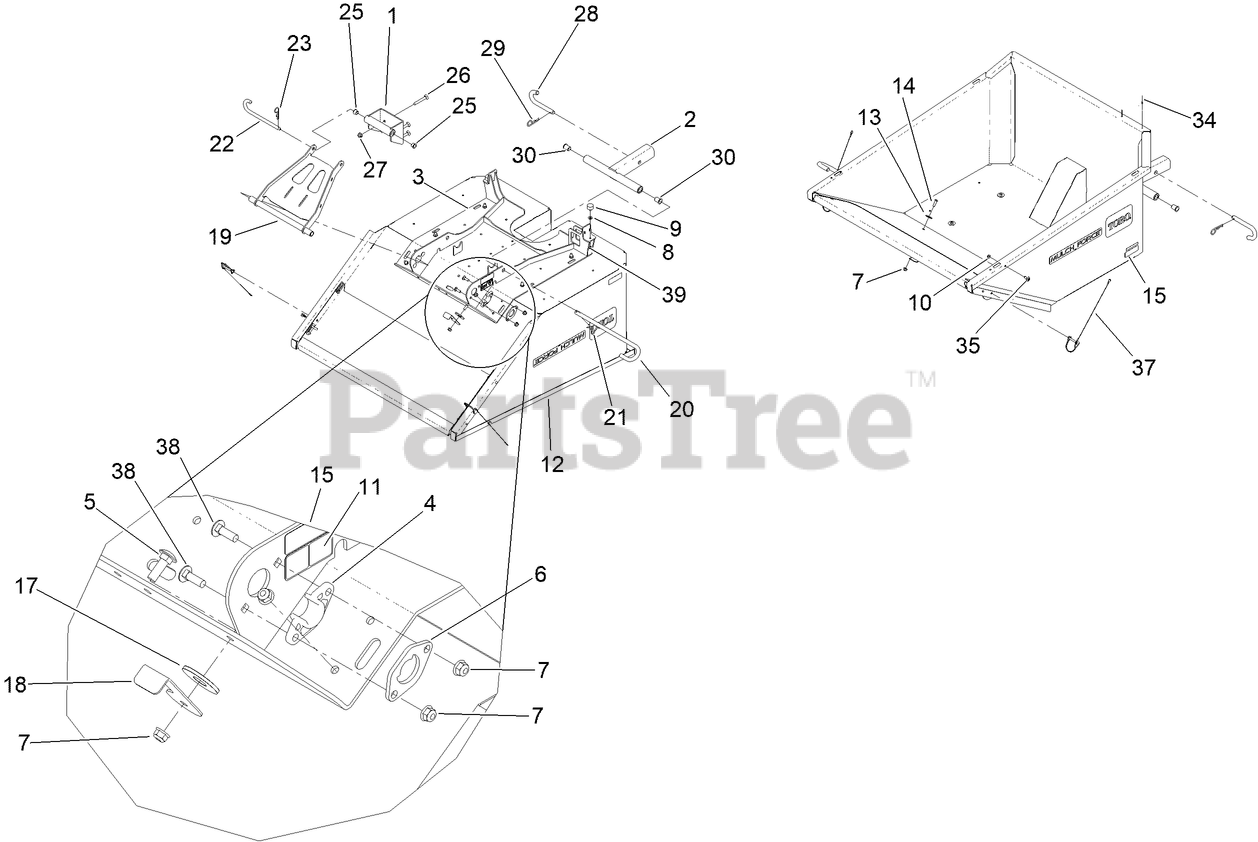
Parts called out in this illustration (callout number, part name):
1	GS DUMP PIN MNT WLDMNT
2	GS DUMP RECEIVER WLDMNT
3	LIFT PLATE WLDMNT
4	BEARING-FLANGE
5	BOLT-CARR
6	GUSSET-COVER
7	NUT-HF, NI
8	WASHER-PLAIN
9	BUMPER-RUBBER
10	NUT-HF
11	DECAL-WARNING
12	MULCH BUCKET
13	WASHER-FLAT
14	SCREW-HSBH
15	DECAL-WARNING, PINCH POINT
17	WASHER-FRICTION, COMPOSITE
18	BRACKET-LOCK, KICKSTAND
19	GS MULCH DUMP STRUT WLDMNT
20	PIN, PIVOT
21	PIN-COTTER
22	PIN-HITCH
23	PIN-HAIR
25	BEARING-FLANGE
26	SCREW-CARR
27	NUT-HF, NI
28	PIN-ATTACH
29	PIN-HAIR
30	BUSHING-FLANGED
34	RIVET-POP
35	SCREW-SHOULDER
37	PIN-SNAP (1/4), LANYARD
38	SCREW-CARR
39	NUT-LOCK, NI
